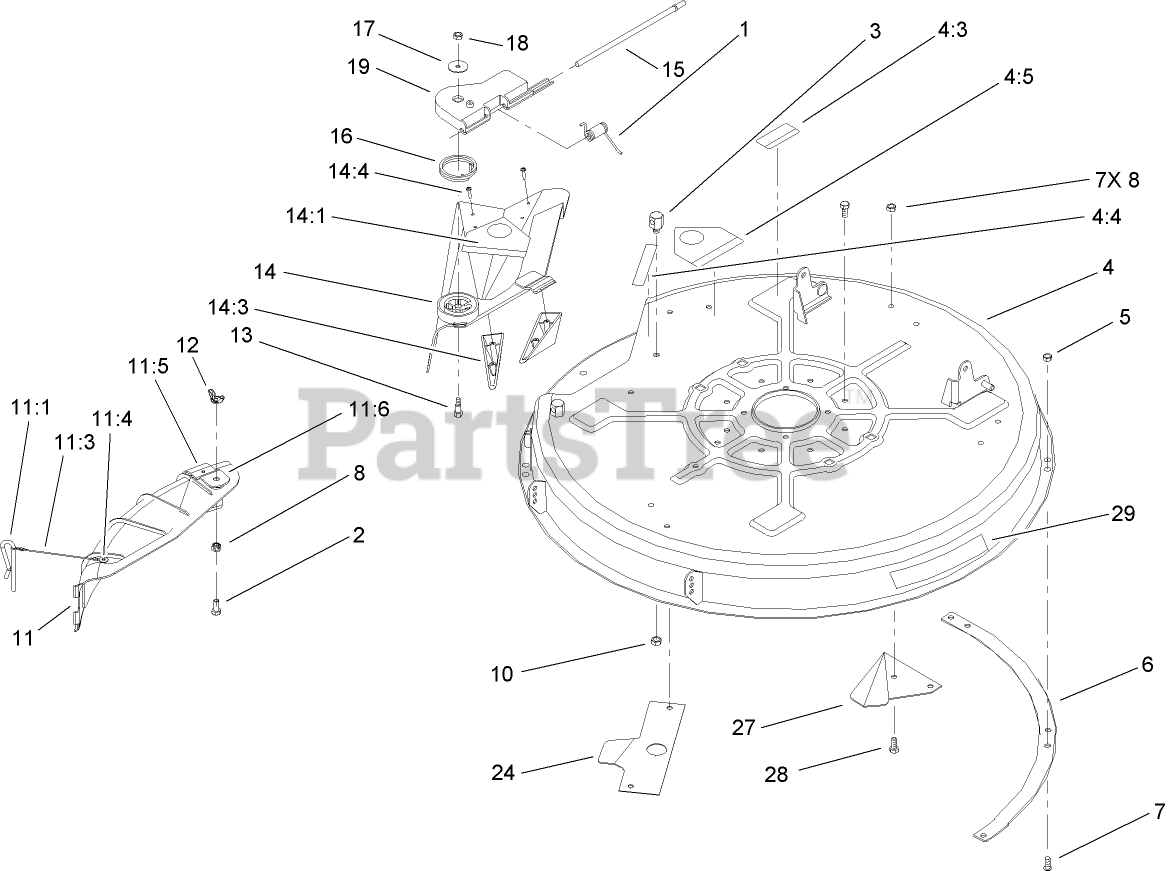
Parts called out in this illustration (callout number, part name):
1	SPRING-TORSION
2	SCREW-HH
3	POST-PIVOT
4	DECK ASM
4:3	DECAL-WARNING
4:4	DECAL-DANGER
4:5	DECAL-DANGER
5	NUT-LOCK, NI
6	RING-DECK
7	SCREW-HH
8	NUT-LOCK, NI
11	DISCHARGE COVER ASM
11:1	PIN-LOCKING, CHUTE
11:3	LANYARD
11:4	RIVET-BLIND
11:5	WASHER-PLAIN
12	NUT-WING
13	BOLT-SHOULDER
14	32 INCH DEFLECTOR ASM
14:1	DECAL-DANGER
14:3	KICKER
14:4	SCREW-PPH
15	ROD-HINGE, DEFLECTOR
16	SPRING-TORSION
18	NUT-LOCK, NI
19	PIVOT-HINGE, DEFLECTOR
24	RAMP-DEFLECTOR
28	SCREW-HH
29	DECAL-RECYCLER
